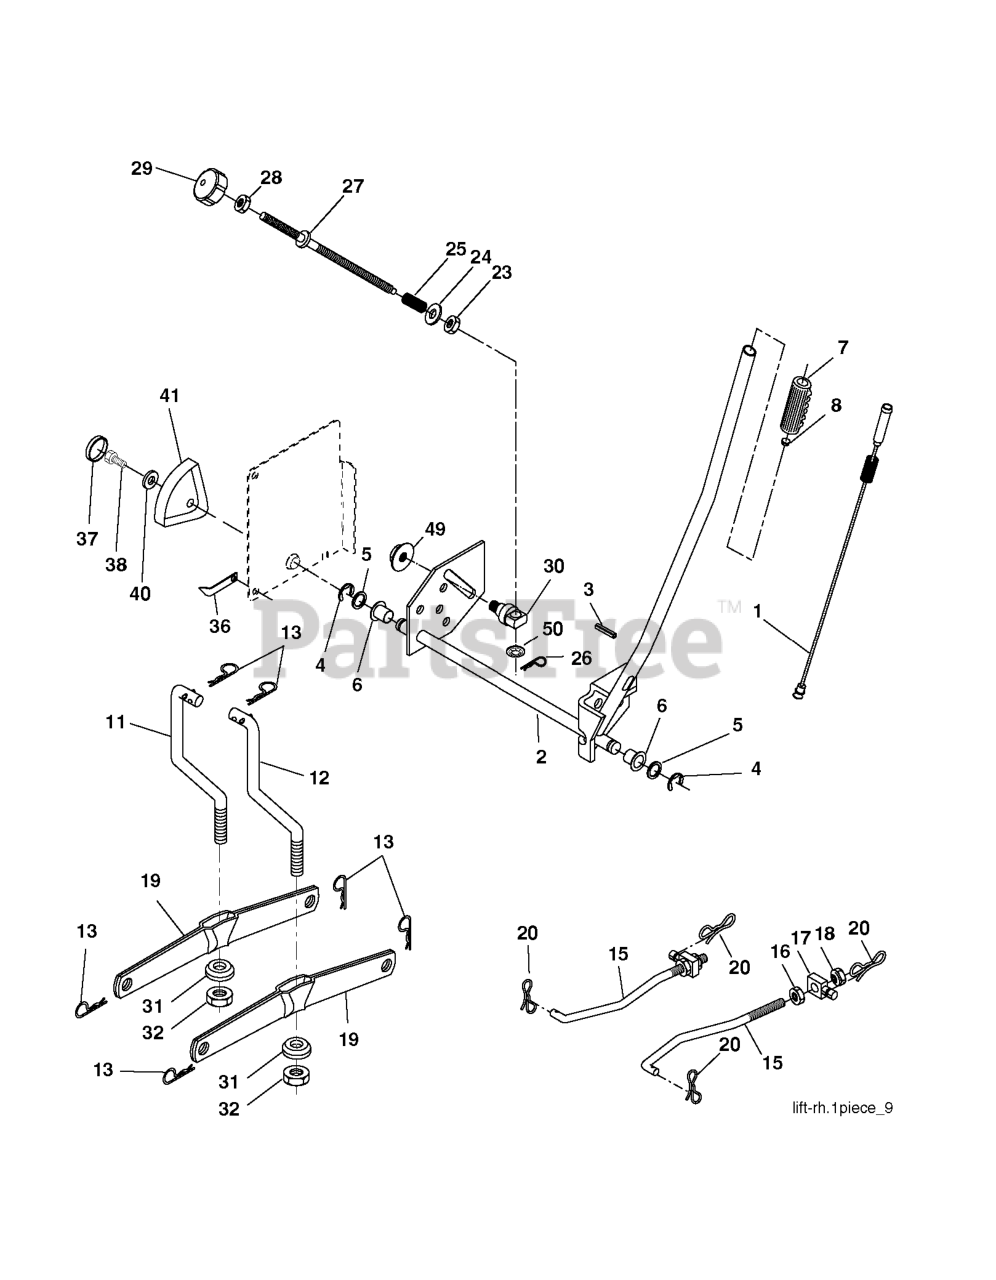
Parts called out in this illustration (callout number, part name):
1	WIRE ASM INNER W/ PLUNGER LT
2	SHAFT ASM R HANDLE
3	PIN GROOVE.
4	RETAINING RING LT
6	BEARING.NYLON
7	GRIP HANDLE
8	REPL BY 532 12 59-25
11	LINK
12	LINK
13	RETAINER-SPRNG RB
15	LINK.SUSPENSION.FRONT
16	NUT.HEX.JAM.1/2-13
18	NUT.LK.W/WSH.1/2.
19	ARM.REAR.SUSPENSION
20	PIN.COTTER.7/16.BOW TI.
26	RETAINER CLIP
27	ROD ADJ LIFT
28	NUT
29	KNOB INF 3/8-16
31	BEARING.PIVOT.LIFT
32	NUT CROWNLOCK 3/8-24
36	POINTER, HEIGHT INDICATOR(2 2)
38	SCREW 5/16-18X1
41	HEIGHT INDICATOR
49	NUT
50	NUT PUSH M
